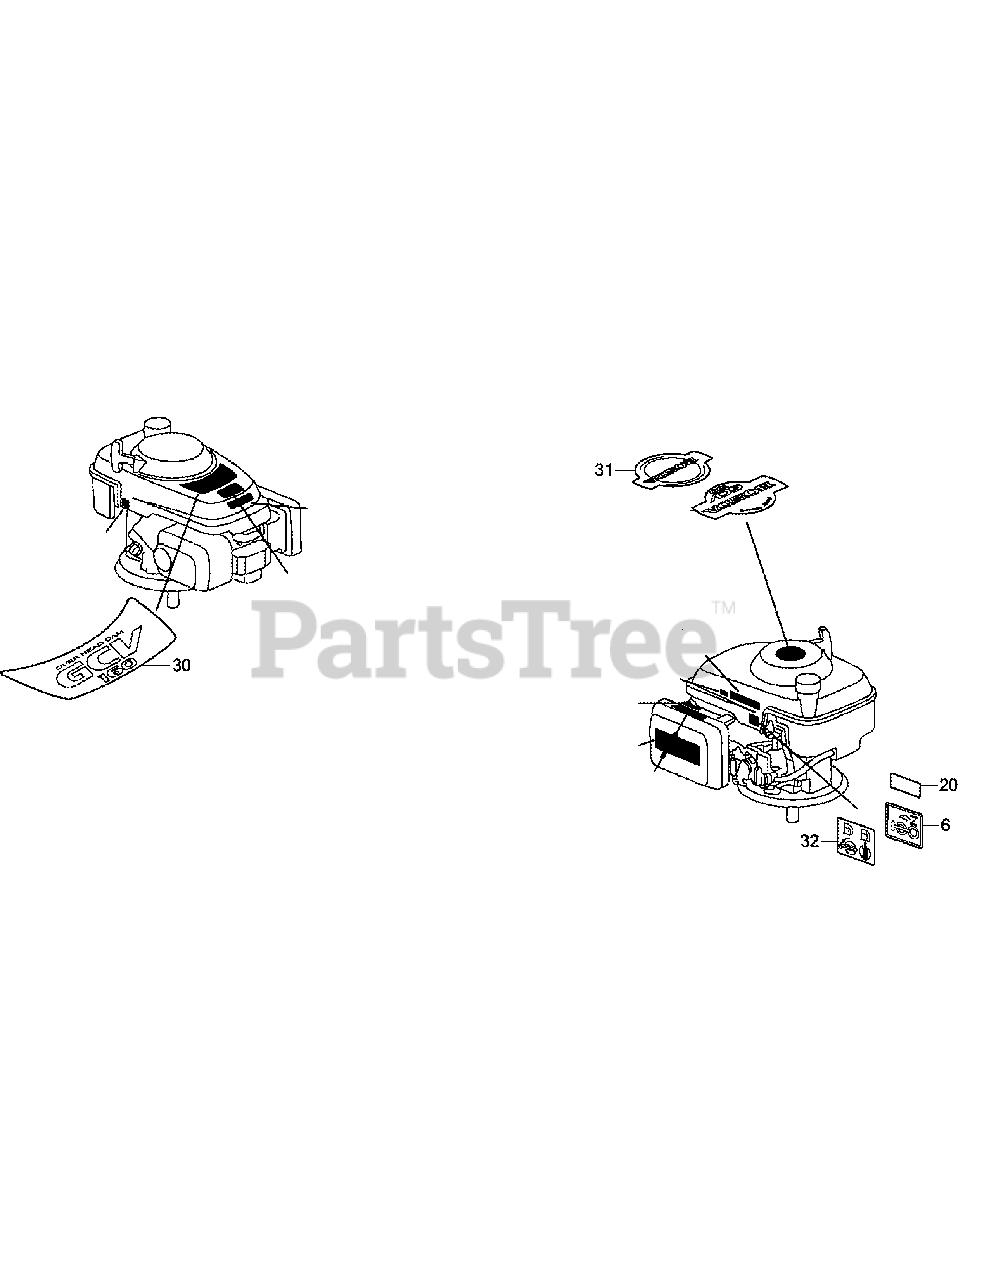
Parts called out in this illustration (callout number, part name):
6	Choke Mark
20	Warning Label
30	Emblem Mark
31	Recoil Cover Mark
32	Fuel Petcock Caution Mark
